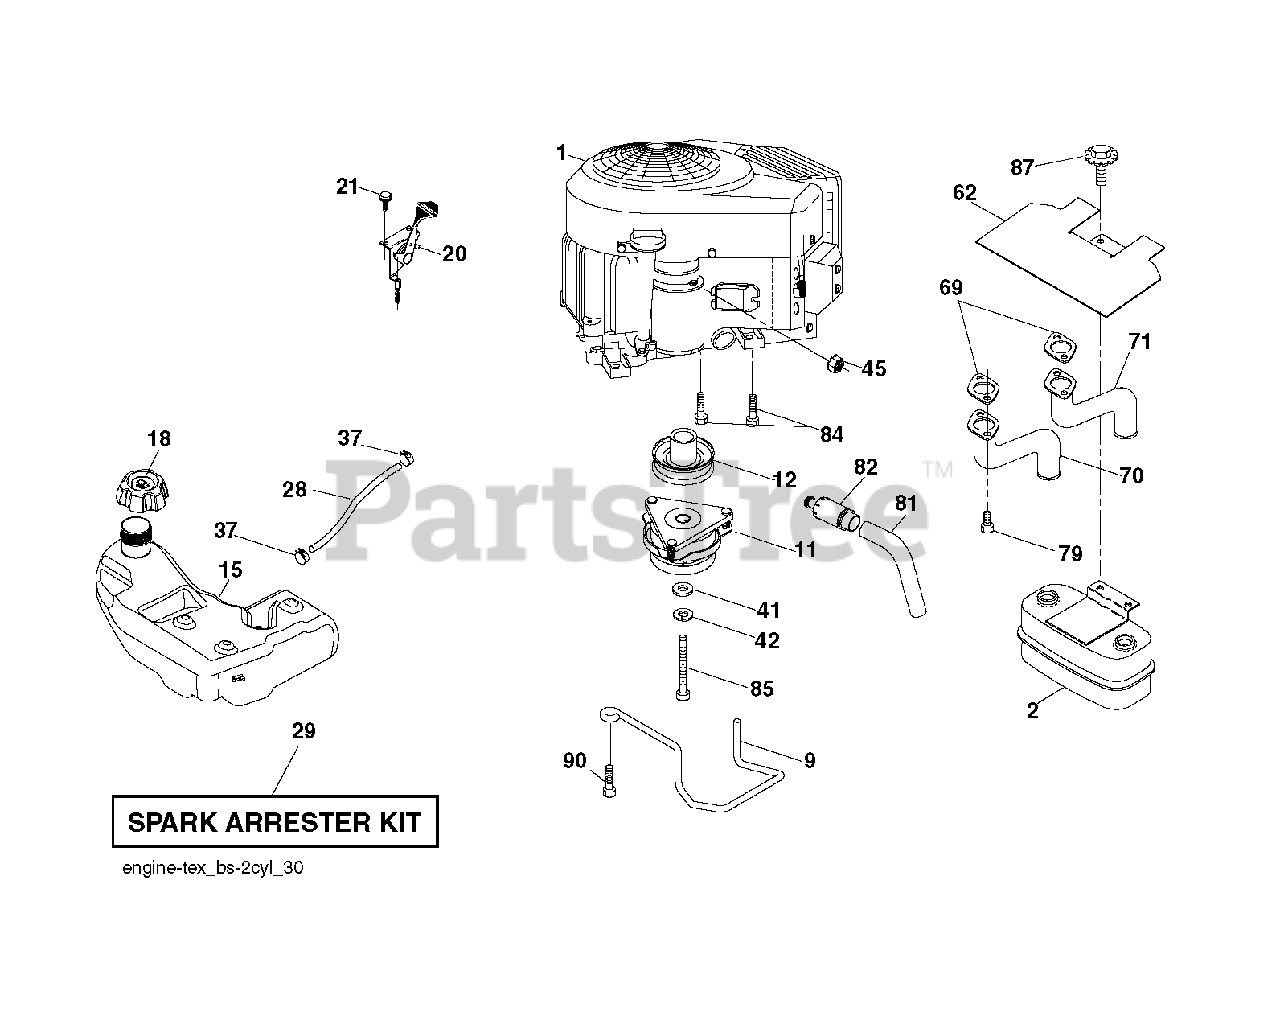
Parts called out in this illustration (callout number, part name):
2	MUFFLER.TWIN.CYL.LOW.TONE
9	KEEPER.BELT.ENGINE.4.2
11	CLUTCH.ELECTRIC.LT.48"*
12	PULLEY.ENGINE.TUFFTORQ
15	TANK.FUEL.4GAL
18	CAP.ASM.FUEL.TANK.3"BL
20	CONTROL.TH/CK.COBRA.B&S.TWN.
21	SCREW.#10 X 0.750.BOS THREAD
29	ARRESTER SPARK (OPTIONAL)
37	HOSE CLAMP
42	LOCKWASHER
45	NUT
62	RP SHIELD HEAT MUFFLER
69	GASKET.MUFFLER
70	TUBE MANIFOLD LH
71	EXHAUST TUBE RH
79	SCREW.SOCKET.HEAD.5/16-18
81	TUBE, DRAIN OIL ASM.
82	PLUG DRAIN OIL EASY
84	SCREW.3/8-16
85	BOLT HEX 7/16-20X4-1/4"
87	BOLT, 5/16-18 X 1 3/4
90	SCREW 3/8-16X1
